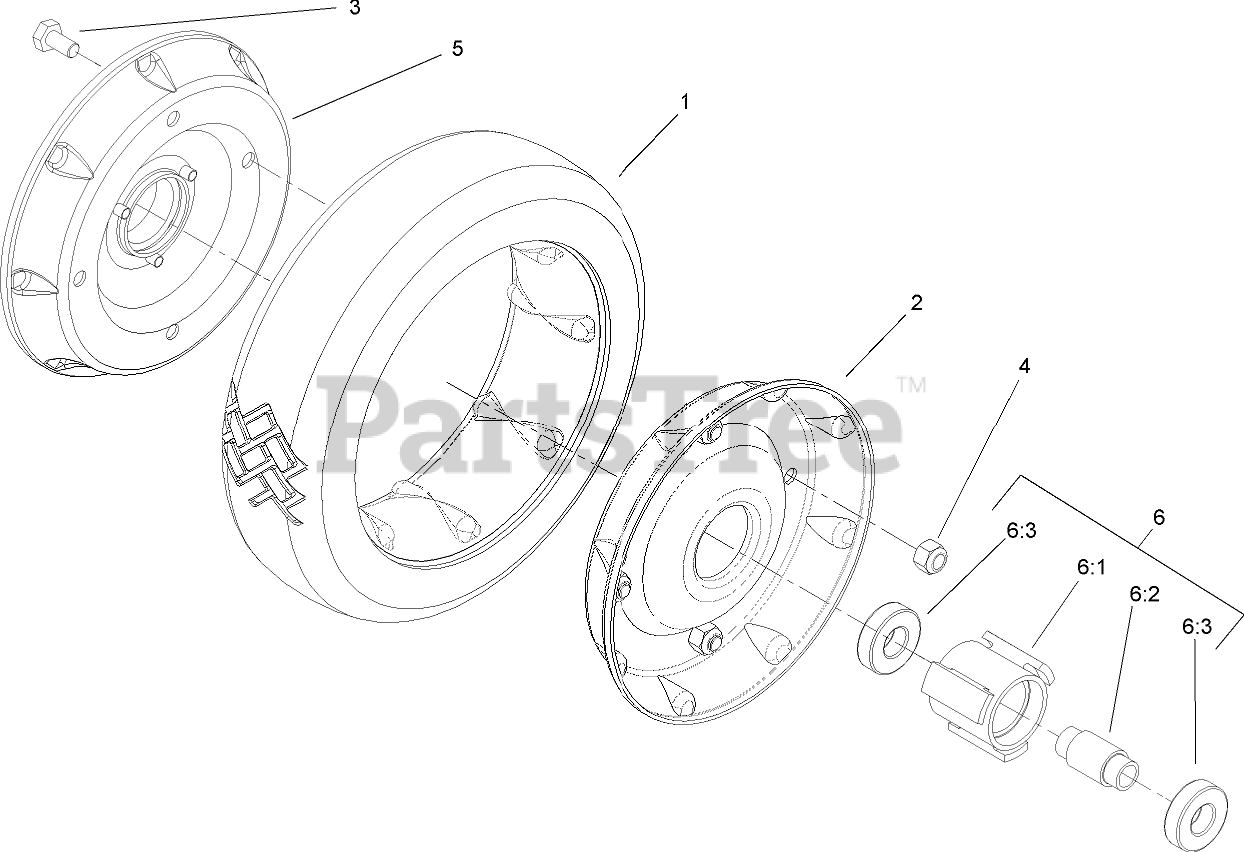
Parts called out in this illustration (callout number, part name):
2	PLATE-WHEEL, HALF
3	SCREW-HH
4	NUT-LOCK, NI
5	WHEEL HALF AND GEAR ASM
6	HUB and BEARING ASM
6:1	HUB-BEARING
6:2	SPACER-BEARING
6:3	BEARING-WHEEL
